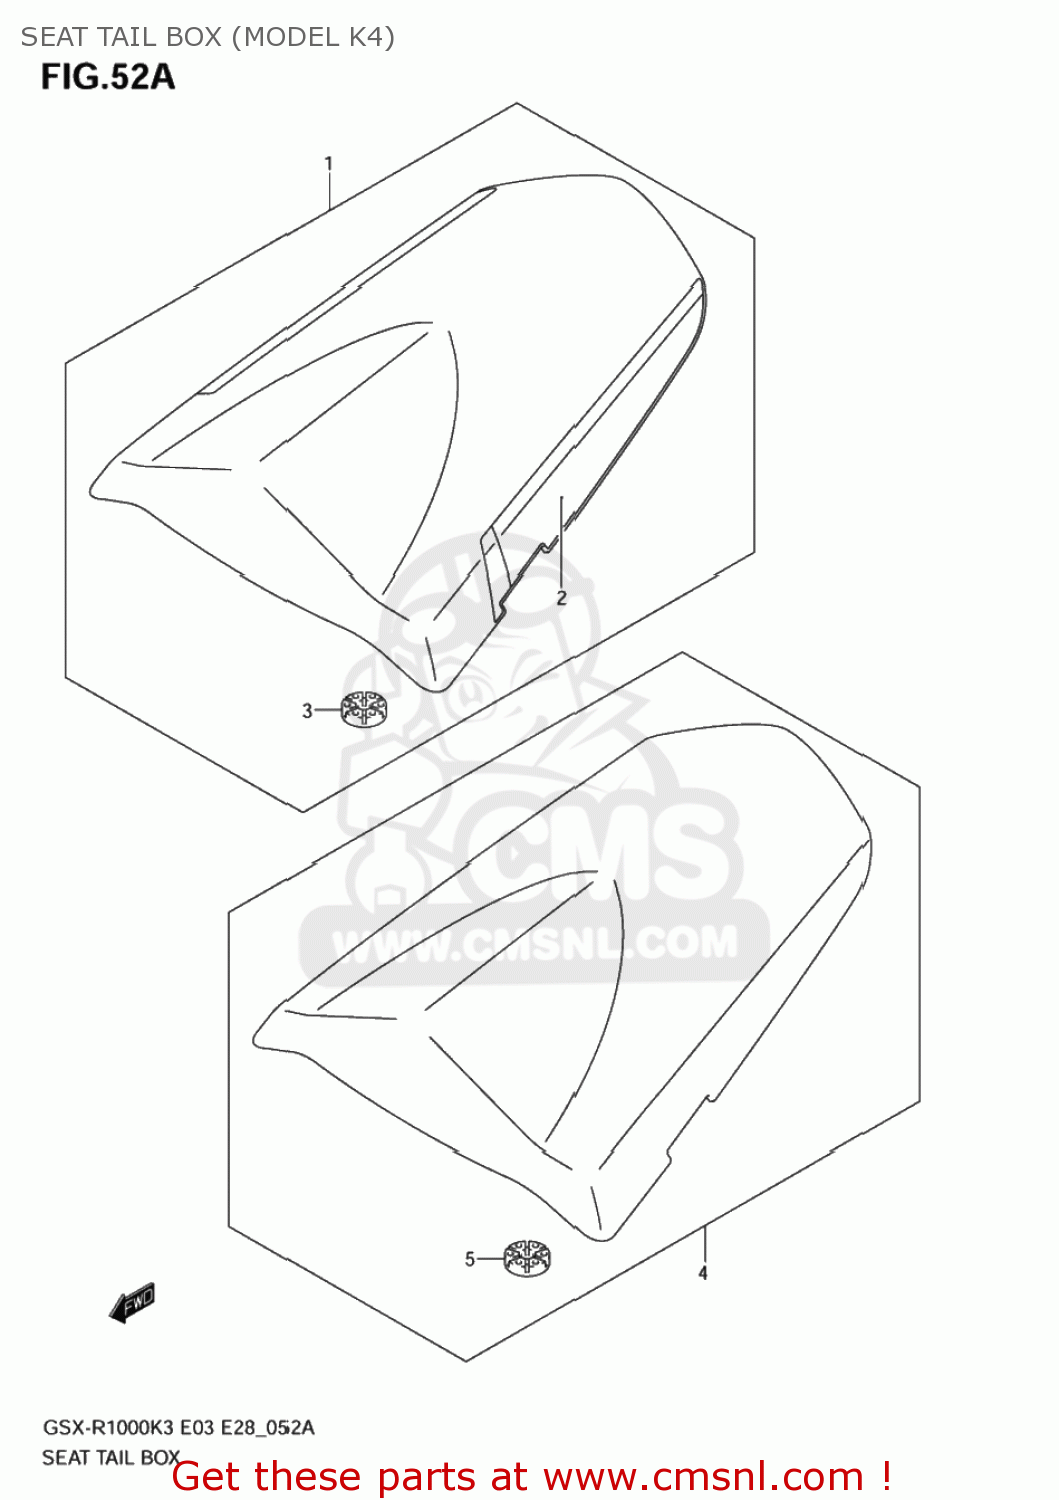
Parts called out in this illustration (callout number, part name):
1	BOX ASSY,SEAT TAIL(WHITE)
2	TAPE SET,BOX SEAT TAIL
3	CUSHION
4	BOX,SEAT TAIL
5	CUSHION
